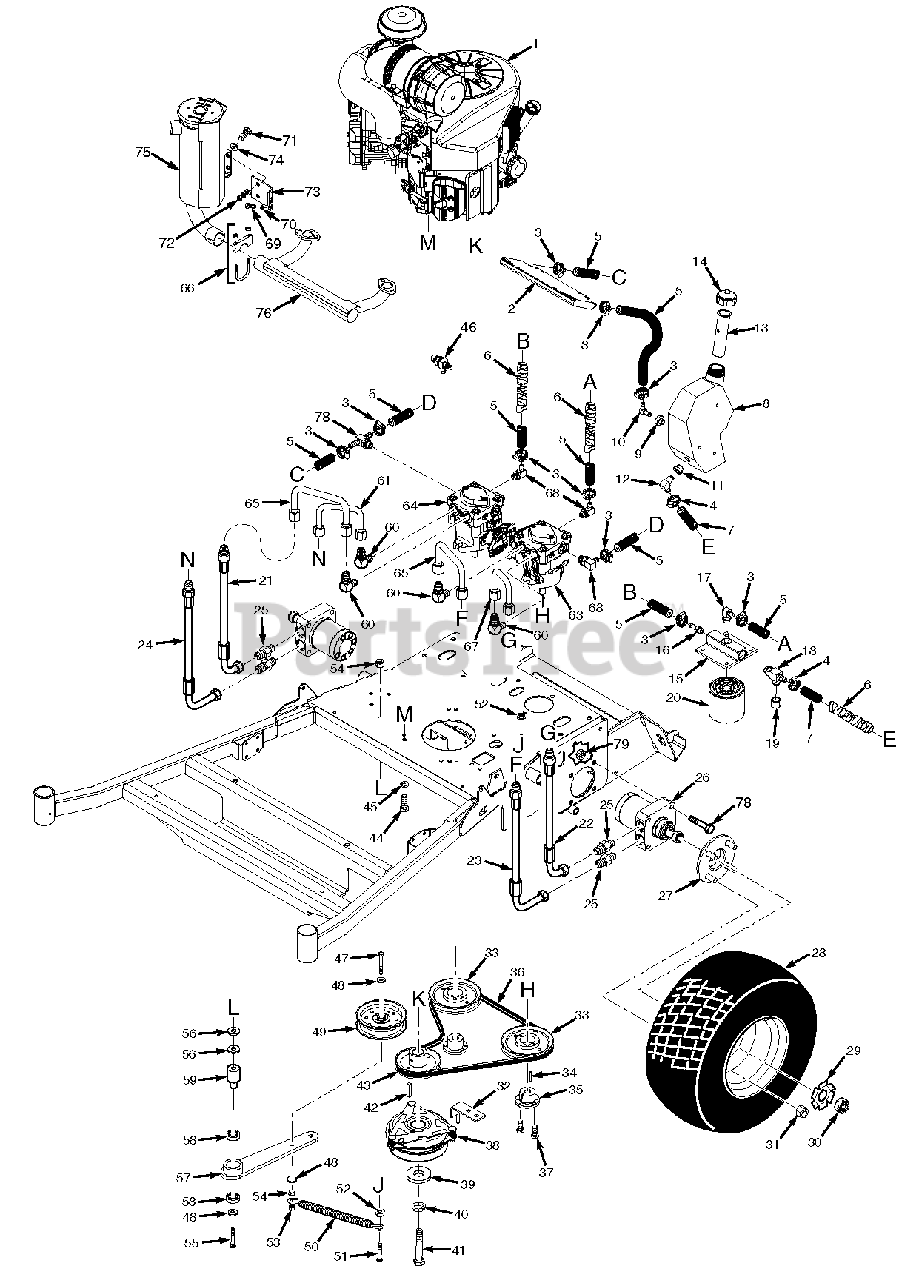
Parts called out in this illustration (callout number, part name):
1	Engine, Kawasaki FX600V
1	Engine, Kawasaki FX691V
1	Engine, Kawasaki FX730V
2	Cooler, Transmission (48V / 52V)
3	Clamp, .69 Max Dia.
4	Clamp, .87 Max Dia.
5	Hose, 3/8 Pushlock
6	Heatshield, Flexible
7	Hose, 1/2 Pushlock
8	Hydraulic Tank Assy.
9	Bushing, .56 Dia, Viton
10	Fitting, 90 Degree - .38 Hose
11	Bushing, .78 Dia. Viton
12	Fitting, 90 Degree - .50 Hose
13	Insert, Filler Neck
14	Cap, Hydraulic Tank
15	Filter Head
16	Fitting
17	Elbow, 90 Degree
18	Tee Fitting, 3/4 O-Ring
19	Cap, 3/4" JIC
20	Oil Filter
21	Hose Assembly
22	Hose Assembly
23	Hose Assembly
24	Hose Assembly
25	Fitting, Union 1/2 x 5/8
26	Wheel Motor
27	Wheel Hub
28	Wheel Assembly (36)
28	Wheel Assembly
28	Rim w/Valve Stem (36)
28	Rim w/Valve Stem
28	Tire, 18 x 8.5-8 (36)
28	Tire, 20 x 10.5-8
29	Lockwasher, Wheel Motor
30	Hex Castle Nut, 3/4-28
31	Wheel Nut
32	Anti-Rotation Bracket (36A)
32	Anti-Rotation Bracket (48V, 52V)
33	Pulley, 5.45 OD - Tapered Bore
34	Key, 5 x 5 x 25mm
35	Tapered Hub, 15mm Bore
36	Belt, Pump Drive (36)
36	Belt, Pump Drive (48 & 52)
37	Bolt, Hex Head 1/4-20 x 1" Gr. 8
38	Clutch w/Tag (36A, 48V, 52V)
39	Flatwasher, 7/16-.469 x 1.75 x .25
40	Lockwasher, 7/16" Spring
41	Bolt, Hex Head 7/16-20 x 2-1/4" Patch
42	Key, 1/4 x 1/4 x 3-1/2"
43	Pulley, 4.75 OD - 1.125" Bore
44	Bolt, Hex Head 3/8-16 x 1-1/4"
45	Lockwasher, 3/8" Spring
46	Oil Drain
47	Bolt, Hex Head 3/8-16 x 2-3/4"
48	Flatwasher, 3/8-.391 x .938 x .105 HD
49	Pulley, 4-1/2" Idler
50	Spring, Transmission
51	Bolt, Hex Head 3/8-16 x 3"
52	Nut, Serrated Flange 3/8-16
53	Nut, Center Lock 3/8-16
54	Nut, Elastic Stop 3/8-16
55	Bolt, Hex Head 3/8-16 x 3-1/4"
56	Flatwasher, 3/8-.375 x 1-1/2 x .059
57	Idler Arm Assy
58	Bearing
59	Idler Pivot, Long
60	Elbow, 90 Degree - 1/2 x 1/2
61	1/2" U-Tube Assembly, 4" Wide
62	Tubing, Oil Drain
63	Pump, LH - 10cc (36)
63	Pump, LH - 10cc w/Shock Valve (48 & 52)
64	Pump, RH - 10cc (36)
64	Pump, RH - 10cc w/Shock Valve (48 & 52)
65	1/2: U-Tube Assembly, 5" Wide
66	Clamp, Muffl er
67	1/2" U-Tube Assembly, 3" Wide
68	Elbow, 90 Degree
69	Bolt, Hex Head M8 - 1.25 x 16 (48V / 52V)
70	Lockwasher, 5/16" Spring (48V / 52V)
71	Bolt, Heax Head 5/16-18 x 1" (48V / 52V)
72	Nut, 5/16-18 (48V / 52V)
73	Bracket, Muffl er (48V / 52V)
74	Flatwasher, 5/16-.344 x .688 x .065 (48V / 52V)
75	Muffl er, Kawasaki (48V / 52V)
76	Exhaust Manifold, Kawasaki (48V / 52V)
